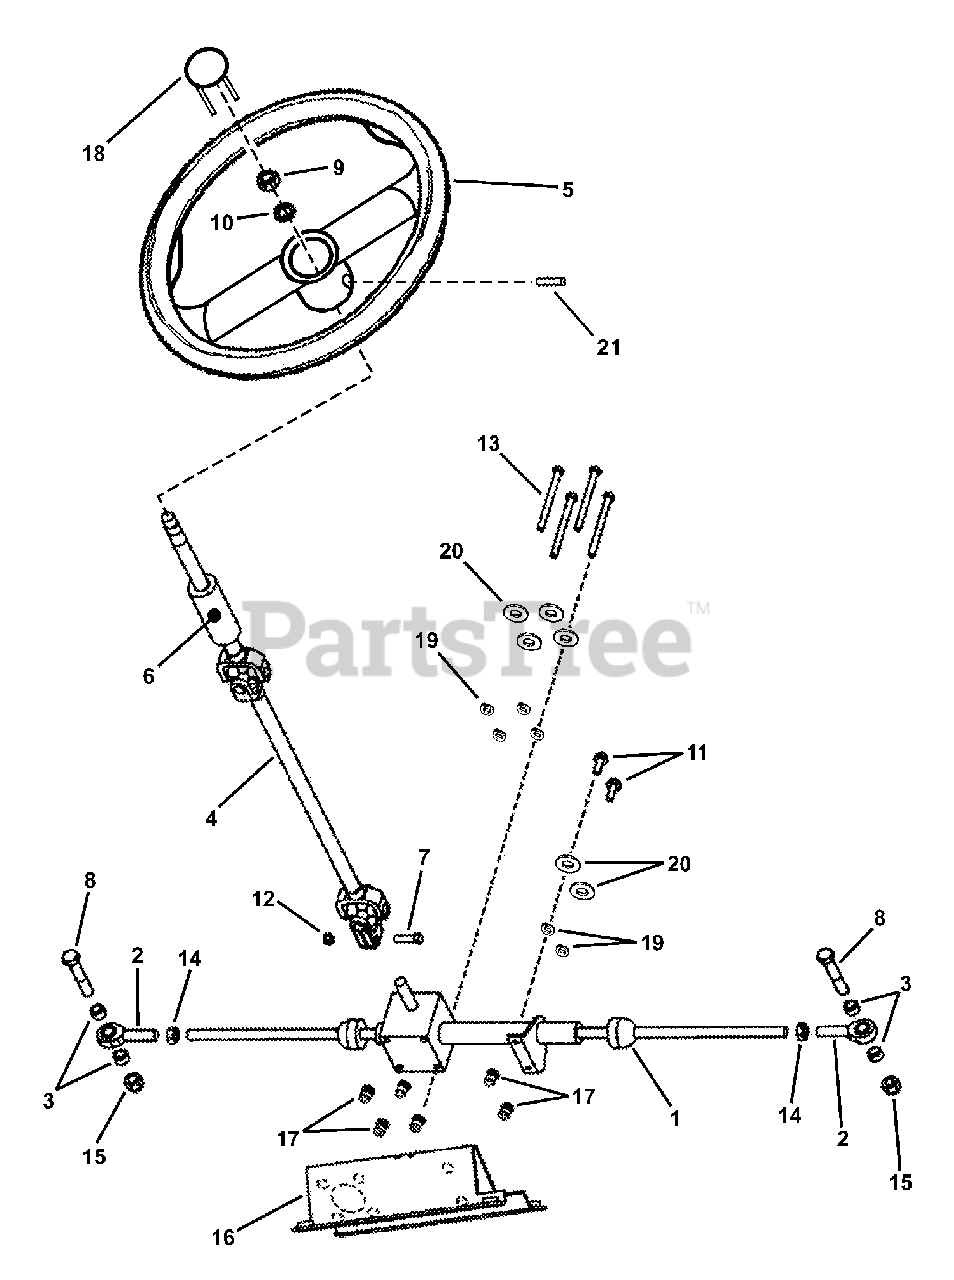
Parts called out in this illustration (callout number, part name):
1	RACK & PINION ASSEMBLY, Steering
2	BALL JOINT, 1/2-20
3	SPACER, 1/2 I.D., 5/8 O.D. x .375
4	STEERING COLUMN
5	STEERING WHEEL
6	COVER, Steering Shaft
7	CAPSCREW, Hex Head, M10-1.50 x 40mm
8	CAPSCREW, Hex Head, 1/2-13 x 2-3/4 GR 5
9	NUT, Hex, M16
10	WASHER, 16mm Split Lock
11	BOLT, Hex Flange Lock, 5/16-18 x 7/8
12	NUT, Hex Nyloc, 10mm-1.50
13	CAPSCREW, Hex Head, 5/16-18 x 3-3/4
14	NUT, Hex Jam, 1/2-20 GR 5 or B
15	NUT, Hex Nyloc, 1/2-13
16	BRACKET ASSEMBLY, Steering
17	INSERT, 5/16-18 Hex Threaded
18	CENTER CAP, Steering Wheel
19	WASHER, .32 x .58 x .08 Split Lock
20	WASHER, .34 x .69 x .08 Flat
21	ROLL PIN, 5/16 x 1-1/2
